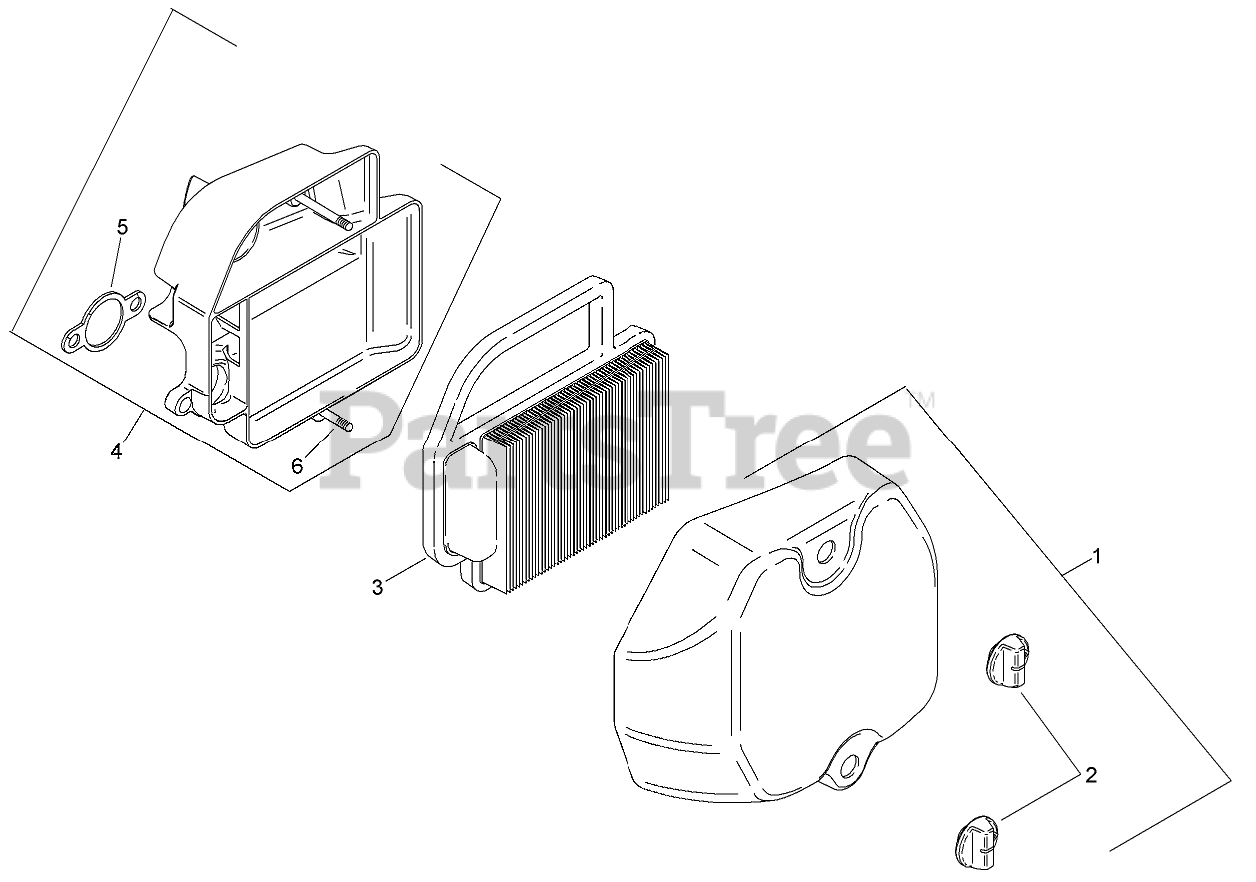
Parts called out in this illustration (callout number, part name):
1	AIR CLEANER COVER ASM
2	KNOB-COVER
3	Element-Cleaner, Air
4	AIR CLEANER BASE KIT
5	Gasket-Base, Air Cleaner
6	STUD-BASE, AIR CLEANER
